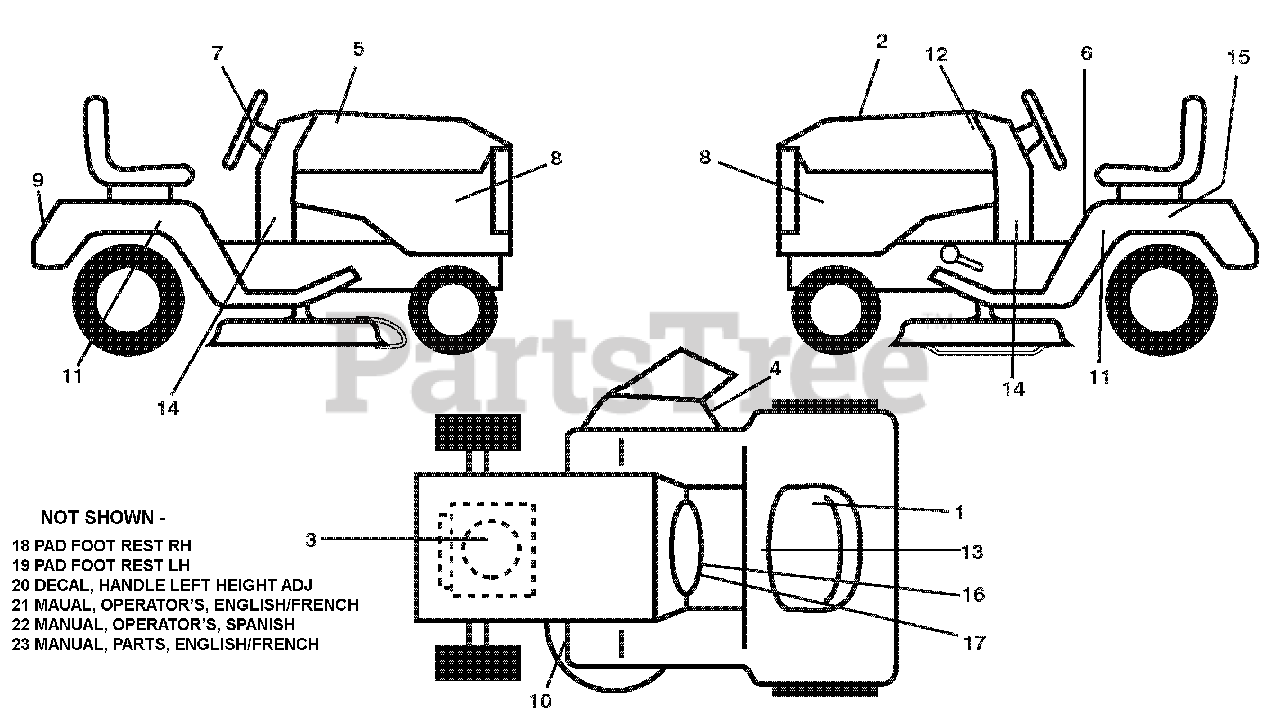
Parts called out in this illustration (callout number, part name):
1	Decal Fender Service
2	DECAL, REPLACEMENT
3	Decal, Engine HP
4	DECAL.MOWER.WARN.KEEP HAND AWY
5	Decal, Hood RH
6	DECAL.FENDER.WARNING.ENG/FR.07
7	Decal, Ins Str Wh
8	Decal, Side Panel
9	Decal, Fender
10	DECAL.V-BELT.SCH.42/46"MEC/ELE
11	Decal, Fender SD Gear Dr.
12	Decal, Hood LH
13	Decal, Flag
14	DECAL, DASH LOWER
15	DECAL.BAT.DAN/POI P/L SYM.WPN
16	Decal, Spark Arrester
17	LABEL. EMISSION. CA
21	OWNER'S MANUAL, ENG/FRE
